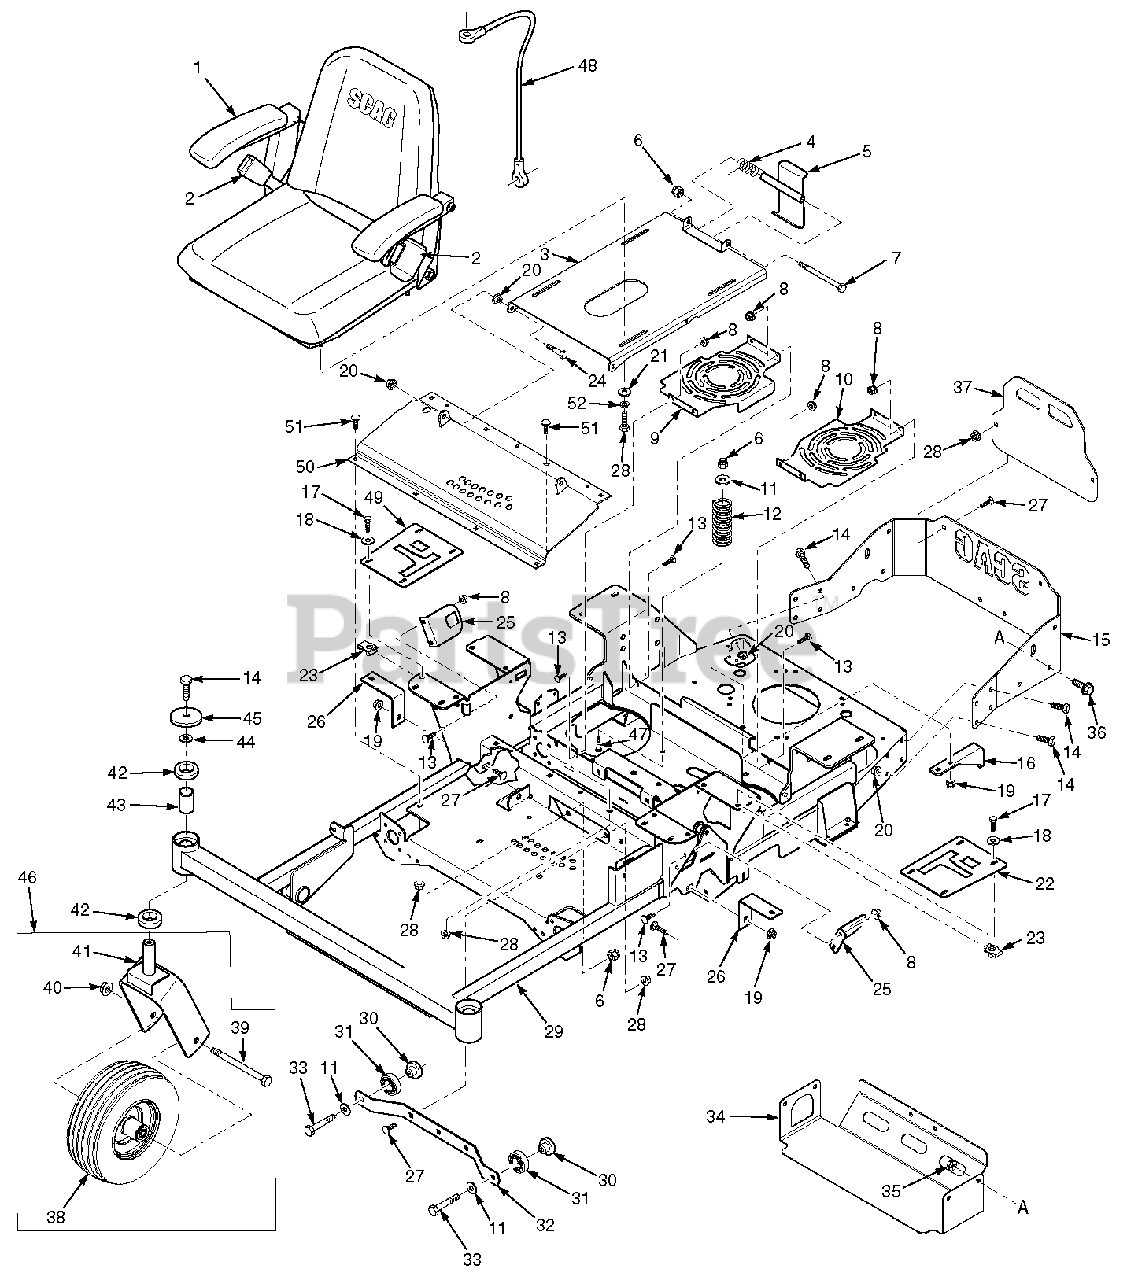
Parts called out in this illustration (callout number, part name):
1	Seat Assembly
1	Back Cushion
1	Bottom Cushion
1	Arm Rest Kit
1	Seat Pan
2	Seat Belt Assembly, Retractable
2	Hardware Package, Mounting
3	Seat Base w/Decal
4	Spring, Seat Latch
5	Seat Latch
6	Nut, Elastic Stop 3/8-16
7	Bolt, Hex Head 3/8-16 x 6"
8	Nut, Serrated Flange 1/4-20
9	Cover, Fan RH
10	Cover, Fan LH
11	Flatwasher, 3/8-.391 x .938 x .105
12	Spring, Seat
13	Bolt, Carriage 1/4-20 x 1"
14	Bolt, Hex Head 3/8-16 x 1"
15	Rear Bumper
16	Bracket, Anti-Rotation
17	Bolt, Hex Head 1/4-20 x 1"
18	Flatwasher, 1/4-.312 x .750 x .065
19	Nut, Elastic Stop 5/16-18
20	Nut, Serrated Flange 3/8-16
21	Flatwasher, 5/16-.375 x .875 x .083
22	Control Plate LH
23	U-Nut 1/4-20
24	Bolt, Hex Head 3/8-16 x 1-1/2"
25	Bracket, Switch Mount
26	Bracket, Tank Mount
27	Bolt, Carriage 5/16-18 x 3/4"
28	Bolt, Hex Head 5/16-18 x 3/4"
29	Main Frame w/Decals
30	Spacer, Bearing
31	Bearing
32	Support, Deck Guide
33	Bolt, Hex Head 3/8-16 x 1-3/4"
34	Heatshield
35	Nut, Serrated Flange 3/8-16
36	Bolt, Hex Head Serrated Flange 3/8-16 x 3/4"
37	Engine Guard
38	Caster Wheel Assembly
39	Bolt, Hex Head 1/2-13 x 6-1/2"
40	Nut, Elastic Stop 1/2-13
41	Yoke, Caster Wheel
42	Bearing
43	Spacer, Caster Bearing
44	Flatwasher, 7/16-.50 x 1.250 x .083
45	Flatwasher, 3/8-.406 x 2.25 x .188
46	Caster Wheel Assembly w/Yoke
47	Bolt, Carriage 3/8-16 x 1-1/4"
48	Cable, Seat Stop
49	Control Plate RH
50	Weldment, Deck Lift Cover w/Decal
51	Bolt, Carriage 5/16-18 x 1/2'
52	Lockwasher, 5/16" Spring
